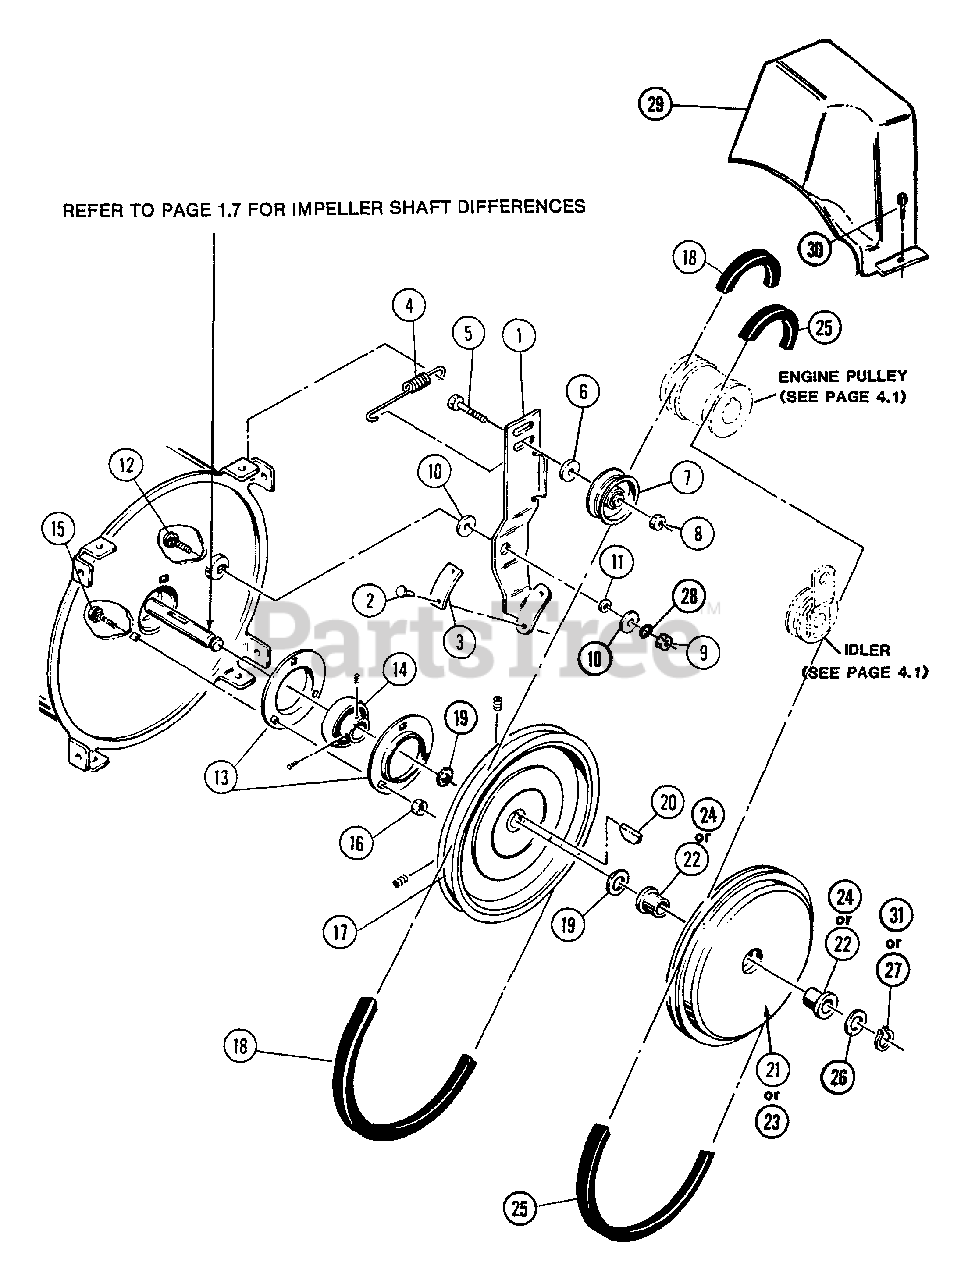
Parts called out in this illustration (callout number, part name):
1	ASSEMBLY, Idler Arm
2	RIVET, 3/16 x .344
3	PAD, Brake
4	SPRING, Extension
5	BOLT, 3/8-16 x 1-1/2" Square Neck Carriage, Grade 2
6	WASHER, 3/8 SAE
7	PULLEY, Idler
8	NUT, 3/8-16 Hex Top Lock
9	NUT, 5/16-18 Hex, Grade B or 5
10	WASHER, 5/16" x 1-1/4" x 3/32" Flat
11	SPACER
12	BOLT, 5/16-18 x 1" Square Neck Carriage, Grade 5
13	HOUSING, Bearing
14	BEARING
15	BOLT, 5/16-18 x 3/4" Short Neck Carriage, Grade 5
16	NUT, 5/16-18 Hex Flange Lock
17	SHEAVE, Blower
18	BELT, Blower
19	WASHER, Thrust
20	KEY, 3/16 x 7/8" Woodruff
21	DRIVE-PLATE (Serial Prefix 03 only)
22	BUSHING
23	DRIVE-PLATE (Serial Prefix)
24	BEARING, Ball
25	BELT, Traction
26	WASHER, 3/4" I.D. x 1-1/8" O.D. Flat
27	RING, Snap
28	WASHER, 5/16 Split Lock
29	COVER, Belt Guard
30	SCREW, 1/4-20 x 3/8" Hex washer Self-Tap
31	RING, Snap
